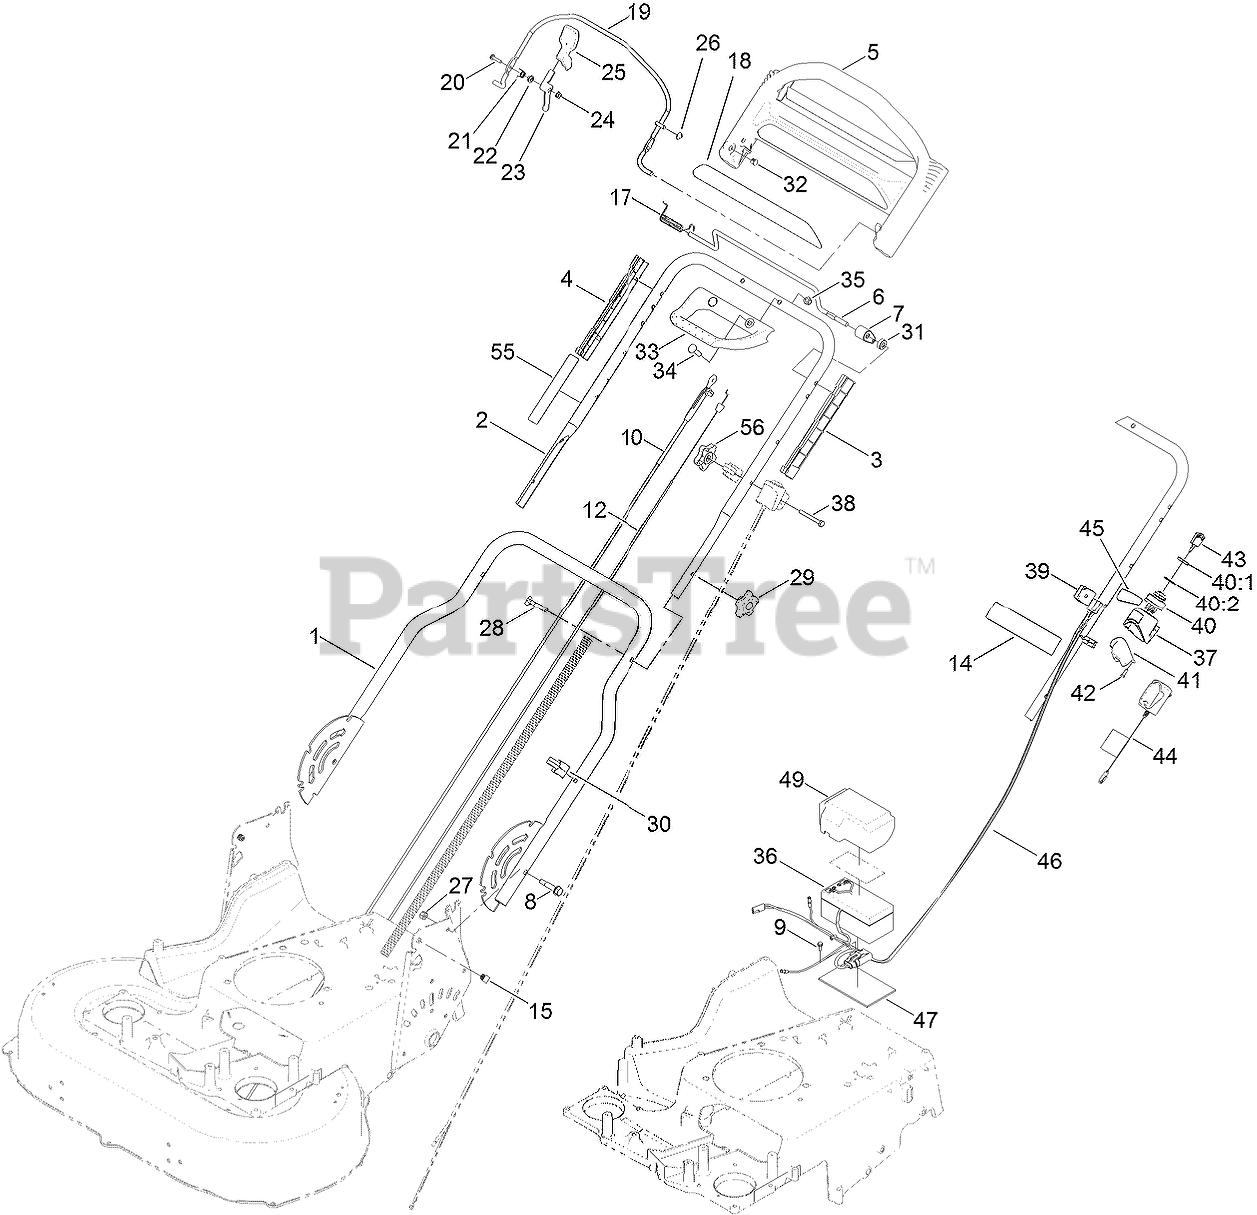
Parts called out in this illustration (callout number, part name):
1	HANDLE-LOWER
2	HANDLE-UPPER
3	GUIDE-LH
4	GUIDE-RH
5	HANDLE-CONTROL
6	BAR-CONTROL, TRACTION
7	LEVER-TRACTION
8	BOLT-SHOULDER, HHF
9	SCREW-TAPTITE
10	CABLE-BRAKE
12	CABLE-TRACTION
14	DECAL-WARNING
15	PLUG-SQUARE
19	BAIL-BRAKE
20	SCREW-HWH
21	SPRING-TORSION
22	SPACER
23	LEVER
24	NUT-LOCK, FLANGE
26	NUT-SPEED
27	NUT-LOCK, NI
28	SCREW-HANDLE
29	KNOB-HANDLE
30	GUIDE-CABLE
31	SPACER
32	PLUG-DOME
33	HANDLE-ASSIST, TRACTION
34	BOLT-CARRIAGE
35	NUT-ACORN
36	BATTERY-WET
37	HOUSING-SWITCH, KEY
38	SCREW-HH
39	ANCHOR-CABLE, UPPER
40	SWITCH-STARTER
40:1	NUT-HH
40:2	WASHER-LOCK
41	COVER-SWTCH
42	SCREW-PPH
44	CHARGER, BATTERY (12V)
45	DECAL-SWITCH, IGNITION
46	HARNESS-WIRE
47	FOAM-BATTERY
49	COVER-BATTERY
55	DECAL-TRACTION, ADJUST
56	KNOB-HANDLE, LOCKING
